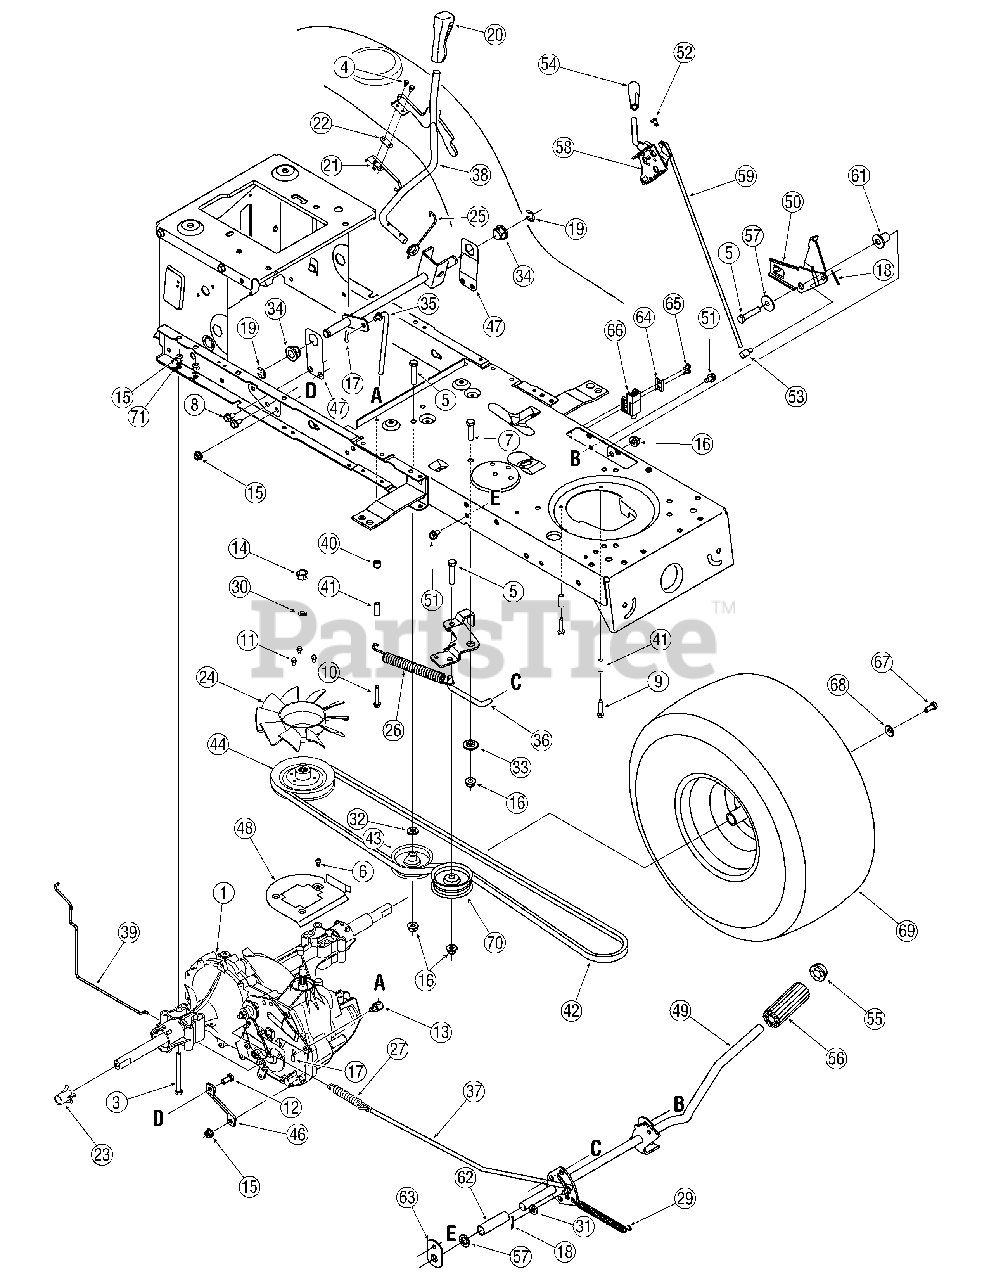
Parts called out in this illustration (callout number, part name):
1	Transmission Assembly, Hydrostatic
2	Control Assembly, Hydrostatic
3	Hex Screw, 5/16-18, 2.75, Gr5,
4	Screw, #8-18, 0.500
5	Hex Screw, 3/8-16, 1.875
6	Screw, B, #10-16, 0.500
7	Hex Screw, 3/8-16, 1.00, Gr5
8	Screw, 5/16-18, 0.625
9	Screw, 1/4-20, 1.250
10	Screw, 1/4-20, 1.625
11	Screw, #12-24, 0.375
12	Hex Screw, 5/16-18, .75, Gr5
13	Ferrule, 5/16-24 x .312 Dia.
14	Nut, Hex Lock, 1/2-20, Gr5
15	Nut, Flange Lock, 5/16-18, Grf, Nylon
16	Nut, Flange Lock, 3/8-16, Grf, Nylon
17	Pin, Cotter, .072 Dia. x 1.13
18	Pin, Cotter, 3/32, 1.0
19	Ring, E-Type, .625 Dia.
20	Grip, Handle, 1/2
21	Spring Switch, Hydro
22	Plate, Insulator Nut
23	Sleeve, .765 x 1.50
24	Fan, 10"
25	Spring, Torsion
26	Spring, Extension, .75 OD x 6.02
27	Spring, Extension, .59 OD x 4.00
28	Ring, Wire
29	Spring, Extension, .50 Dia x 6.37
30	Washer, Lock, 1/2
31	Washer, Flat, .344 x .750 x .120
32	Washer, Flat, .407x.812x.135
33	Spacer, Shoulder, .625 ID x .169
34	Bearing, Hex Flange
35	Control Rod, Hydrostatic
36	Declutching Rod
37	Brake Rod, Hydrostatic
38	Control Handle, Hydrostatic
39	Bypass Rod, Hydrostatic
40	Spacer, .254 x .50 x .390
41	Spacer, .260 x .372 x 1.030
42	Belt, V-Type
43	Idler Pulley, Flat 2.75 OD
44	Pulley, Input, 5.0 OD
51	Screw, 5/16-18, 0.50,
52	Screw, 1/4-14, 0.625
53	Ferrule 1/4-20
54	Not used in this application
55	Push Cap, 5/8
56	Foot Pad, 4.0
57	Washer, Flat, .406 x 1.25 x .157
58	Lever, Parking Brake
59	Control Rod
60	Spacer, Shldr, .38 x.50 x .15
61	Spacer, Flange, .390 x .671 x .95
62	Spacer, .640 x .76 x 2.63
63	Support Bracket, Pedal
64	Plate, Switch
65	Screw, #10-16, 0.500
66	Switch, Interlock
67	Screw, 5/16-24, .750, Gr5
68	Bell Washer, .34 x .872 x .060
70	Idler Pulley, Flat 2.75 OD
71	Washer, Lock 5/16 Ext. Tooth
